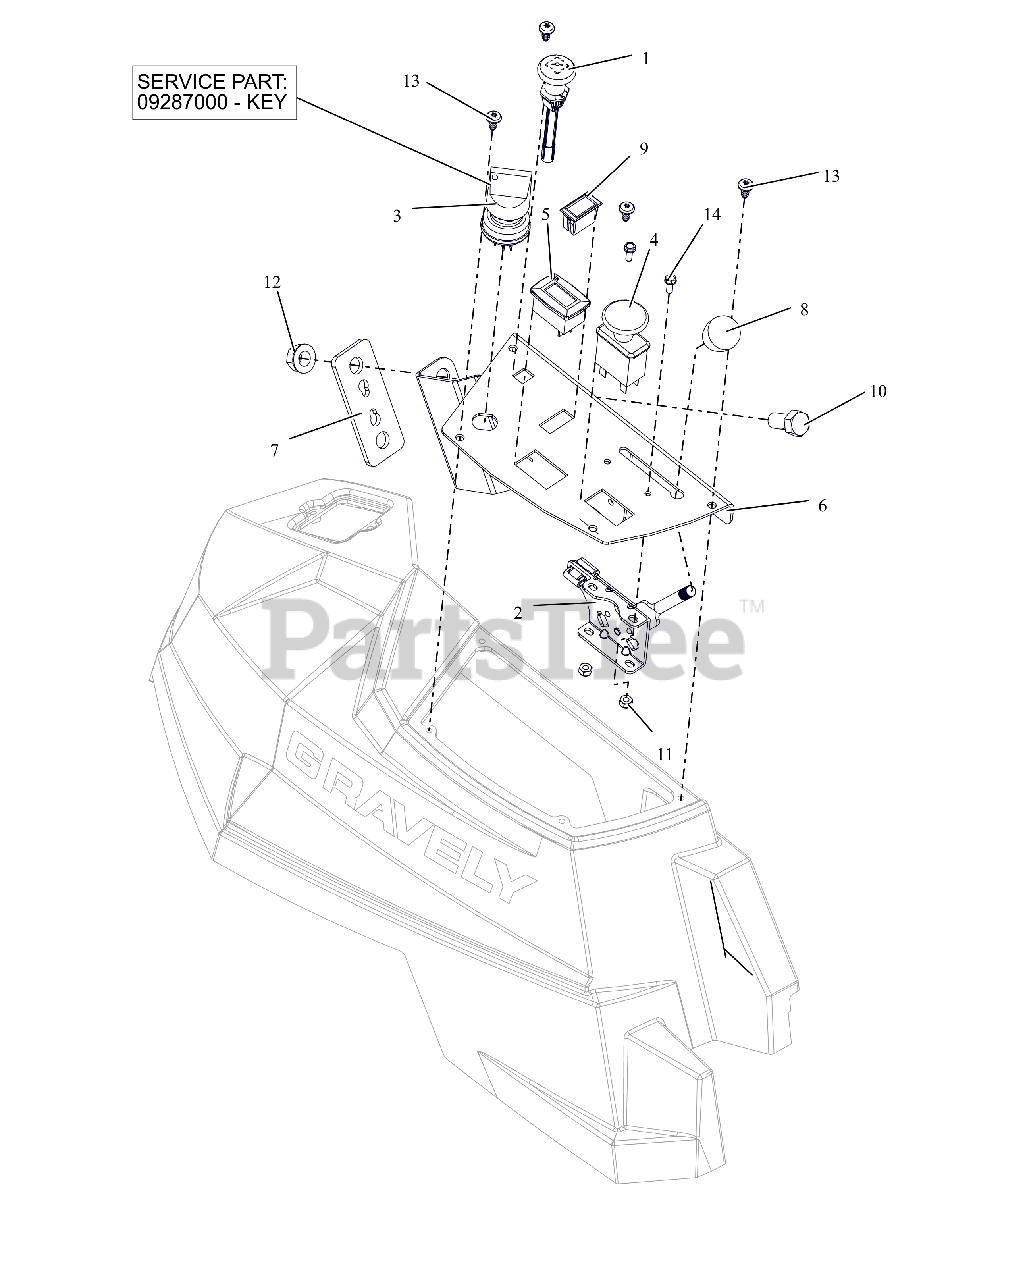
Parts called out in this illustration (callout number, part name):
1	CABLE - CHOKE, SNAP-IN
2	CABLE, PRO THROTTLE CONTROL
3	SWITCH, IGNITION
3	KEY, W/ SHIELD
4	SWITCH, CLUTCH
5	METER, HOUR W/MAINTENANCE
6	PANEL, HD CONTROL
7	PLATE, CONTROL PANEL SPACER
8	KNOB-CONTROL-BLACK .38-16X.50
9	SWITCH,BLANK
10	BLT, HEX .50-13X1.00 G5 ZCC
11	NUT-LK-NYL #10-24 G2 ZCC
12	NUT-LK-TOP-FLG .500-13 GF ZCC
13	SCR-PAN .25-15X.50 6L H/LZB500
14	BLT, HWH #10-24X.50 ZCC
